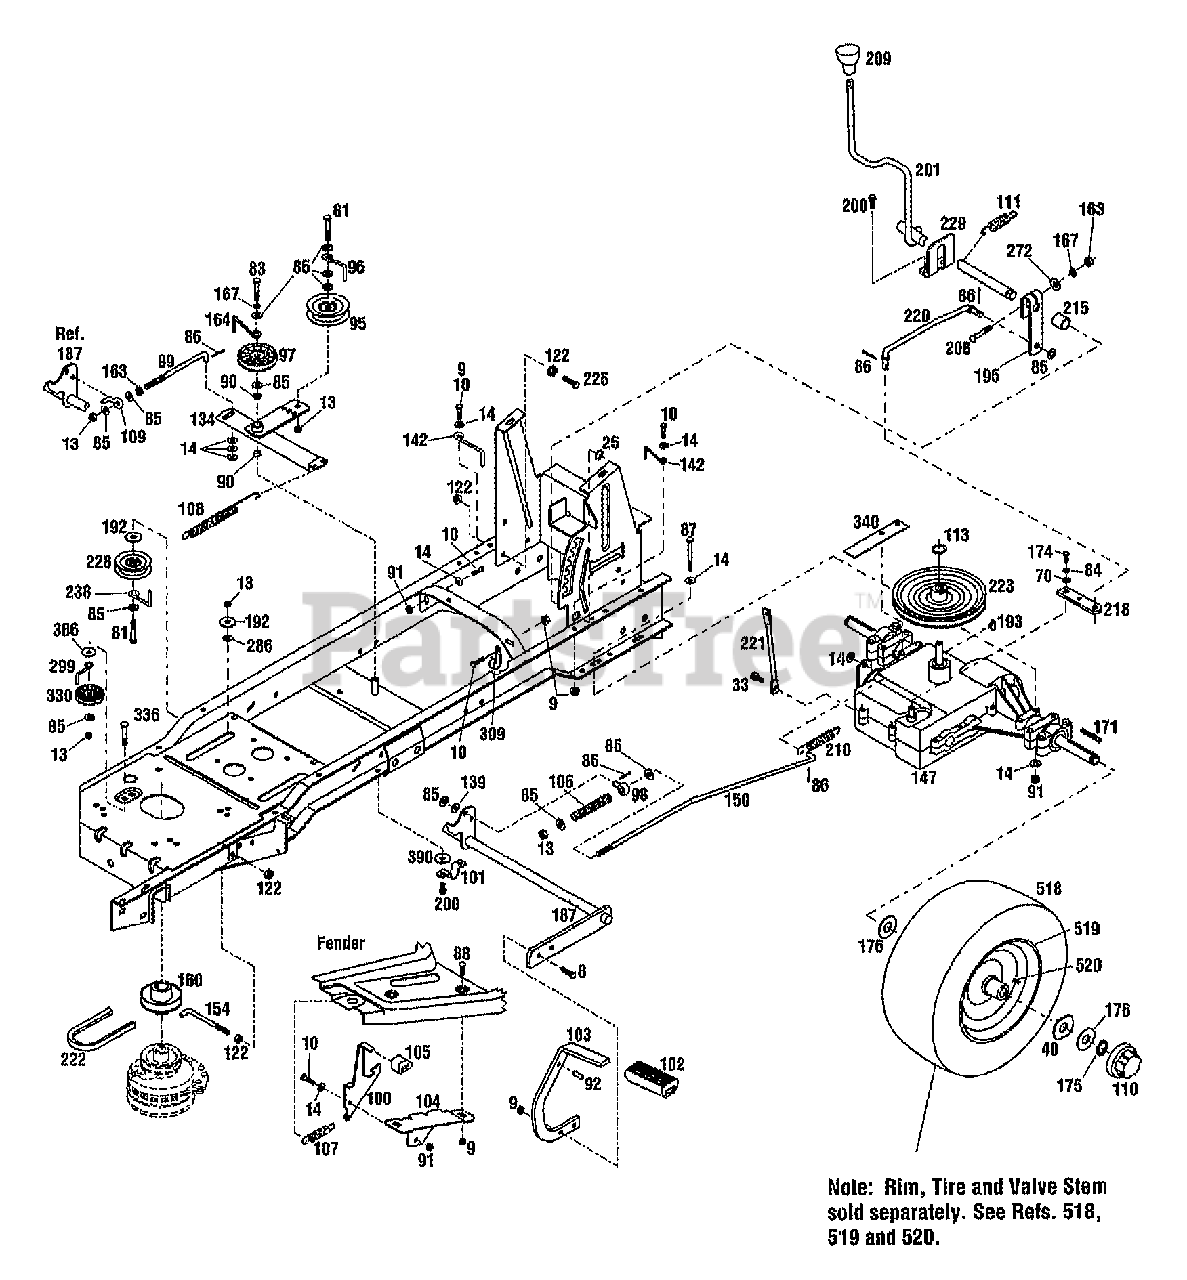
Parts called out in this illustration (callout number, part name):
8	SCR-HH 5/16-18X1.0 G5 ZP
9	NUT-HFLK 5/16-18 ZP
10	SCR-HHC 5/16-18X.75 GR 5 ZP
13	NUT-LOCK 3/8-16
14	WASHER-FLAT 5/16 SAE
25	RING-RETAIN EXT .707 ID
33	SCR-HFLK 5/16-18X.75
40	WASHER-SPEC .75X2.50
70	WASHER-FLAT 1/4 SAE
81	SCR-HH 3/8-16X2.0 G5 ZP
83	SCR-HH 3/8-16X1.75 G5 ZP
84	WASHER-LK .25 ZP
85	WASHER-FLAT 3/8 SAE
86	PIN-COTTER .09X.75 ZP
87	SCR-HH 5/16-18X2.75 G5 ZP
88	SCR-CARR 5/16-18X.62 G2 ZP
90	BUSHING-.5X.5 NYLON FLNG
91	NUT-TOP/LK 5/16-18 ZP
92	PIN-DRIVE .312X.75
96	GUIDE-BELT
97	PULLEY-IDLER
98	SWIVEL
99	ROD-CLUTCH
100	LATCH-BRAKE LOCK
101	CLIP-CLAMP .75 ID
102	PAD-FOOT PEDAL
103	PEDAL-BRAKE
104	BRKT-BRAKE LOCK
105	PAD-BRAKE
106	SPRING-COMPRESSION
107	SPRING-EXTENSION
108	SPRING-EXTENSION
109	ROD-PIVOT
110	CAP-HUB
111	SPRING
113	RING-RETAIN .625 ID
122	NUT-HFLK 3/8-16 ZP
134	ARM-IDLER
139	WASHER-FLAT .375DIA
142	GUIDE-BELT
147	TRANSAXLE
150	ROD-BRAKE
154	RETAINER-CLUTCH
160	PULLEY-ENGINE
163	NUT-HEX 3/8-16 ZP
164	GUIDE-BELT
167	WASHER-LK .375 @ DEPL
171	KEY-.188 SQ X 2.0
174	SCR-HHC 1.4-28 X .50
175	RING-RET."E".577 ID
176	WASHER-1.87X.765X.06 SPECIAL
187	ASSM-BRAKE PEDAL
192	WASHER-1.12X.378X.125
193	KEY-WOODRUFF .188X.75
195	ARM-SHIFT SHAFT
200	SCR-HFLK 5/16-18X.75
201	ARM-GEAR SHIFT
208	BOLT-CARR 3/8-16X2 1/4
210	SPRING-EXTENSION
215	SPACER
218	ARM-TRANSMISSION
220	ROD-SHIFT
221	SUPPORT-TRANS
223	SHEAVE-TRANSMISSION
225	SCR-HH 3/8-16X1.5 G5 ZP
228	IDLER-SHEAVE 3" X 1"
229	GUIDE-SHAFT
238	GUIDE-BELT
272	WASHER-FLAT 1.25X.406X.179
286	WASHER-.75X.406X.092
299	GUIDE-BELT
309	CLIP-J
330	PULLEY-IDLER
336	BOLT-CARR
340	STOP-TRANSMISSION
386	WASHER-1.06X.531X.1 ZP
390	WASHER-.632X.39X.0329
518	TIRE-20X8.00-8
519	RIM-TIRE
520	STEM-VALVE
